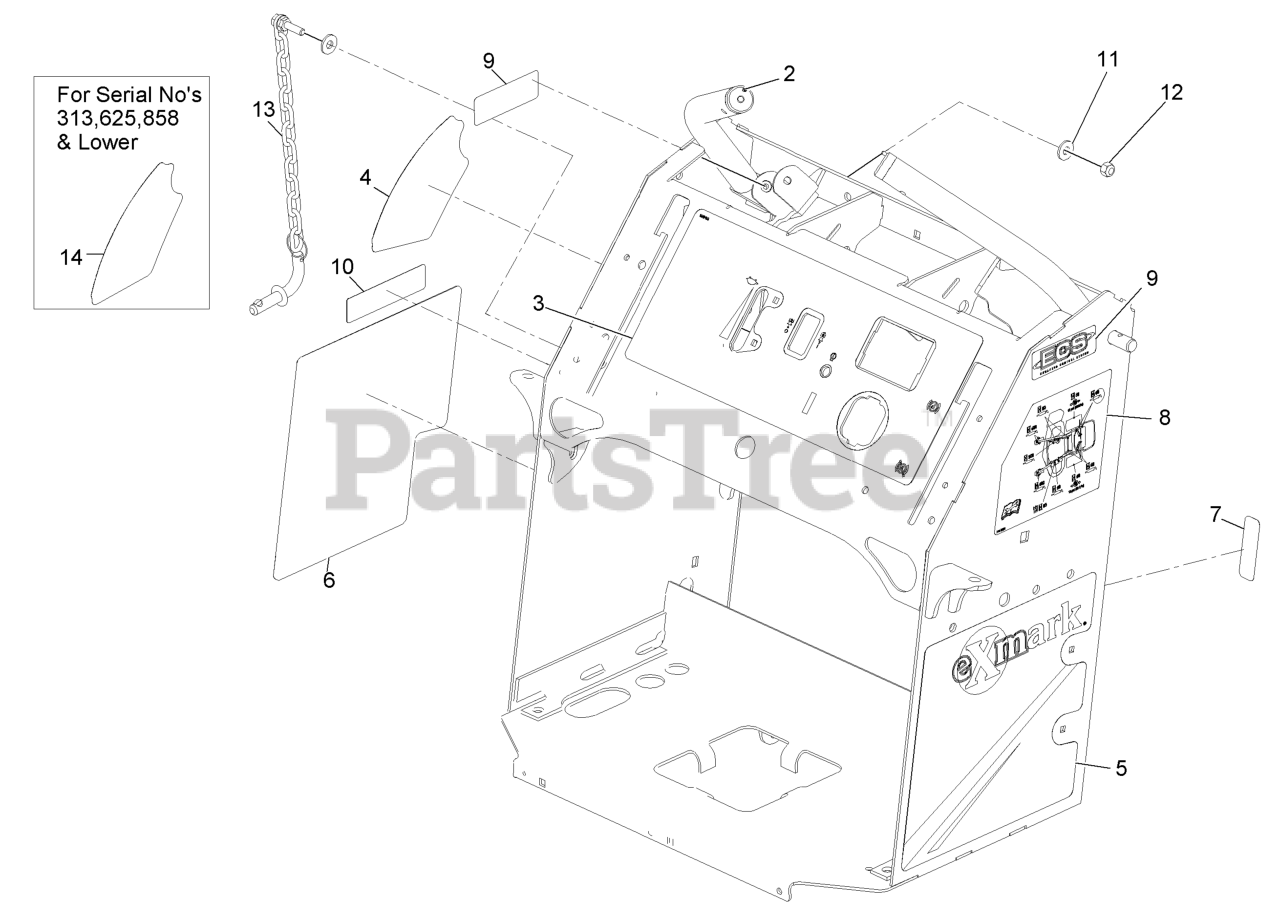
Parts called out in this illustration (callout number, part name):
3	DECAL-CONTROL PANEL EFI
4	DECAL-HEIGHT OF CUT
5	DECAL-LH PANEL
6	DECAL-RH PANEL
7	DECAL-FUSE
8	Decal-Service Aid
9	DECAL-ECS LOGO
10	DECAL-ARRESTER, SPARK
11	WASHER-FLAT
12	NUT-LOCK, NI
13	HOC PIN ASM
14	DECAL-HEIGHT OF CUT
